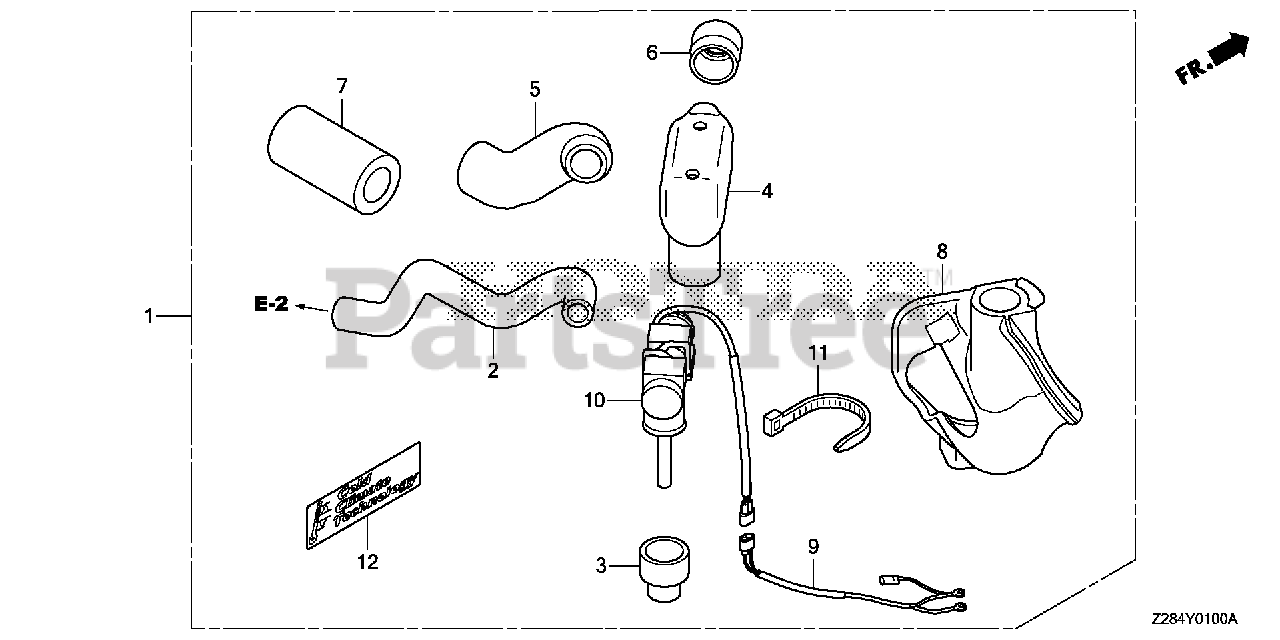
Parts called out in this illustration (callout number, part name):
1	HEATER KIT, BREATHER
2	TUBE A, BREATHER
3	TUBE B, BREATHER
4	INSULATOR, BREATHER HEATER
5	INSULATOR, BREATHER TUBE
6	TUBE C, BREATHER
7	INSULATOR B, BREATHER TUBE
8	INSULATOR, AIR IN. JOINT
9	SUB-WIRE ASSY.
10	HEATER ASSY., BREATHER (L)
11	BAND, HARNESS (BLACK)
